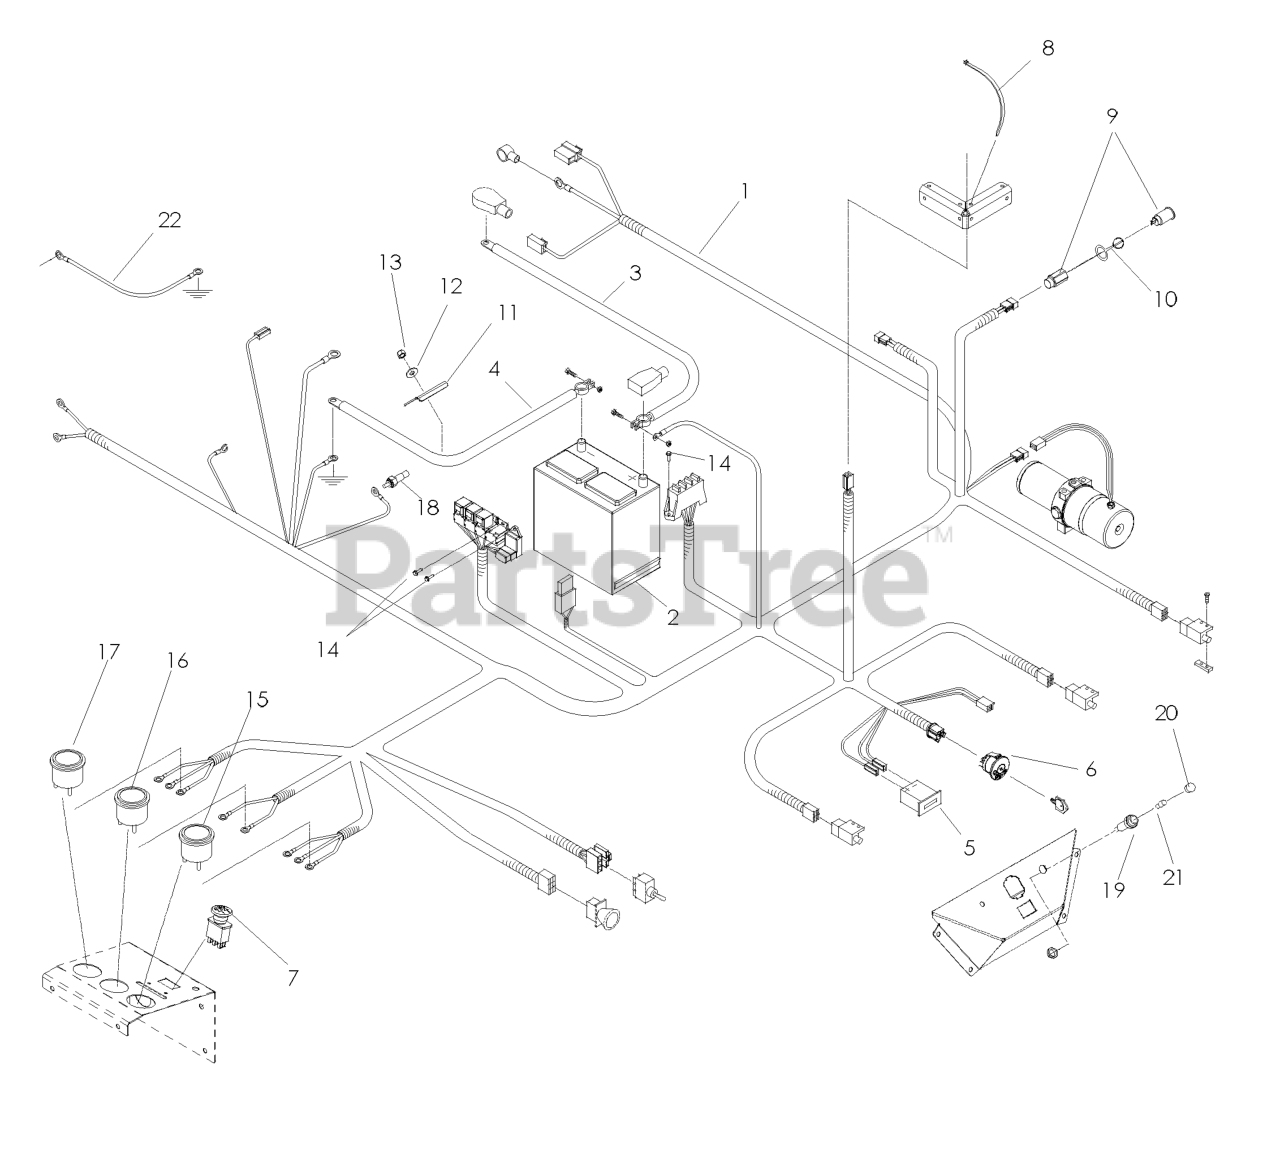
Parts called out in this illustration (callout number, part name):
3	CABLE, POS.
4	CABLE, NEG.
5	HOUR METER
6	RP IGNITION SWITCH
7	SWITCH, PTO 10 AMP
8	TIE, PLASTIC
9	POWER SOURCING HSG
10	POWER SOURCE CAP
12	WASHER 5/16 FLAT
13	NUT 5/16 NYLOC
14	SCR #10-12X3/4 HEX WAS HD ZD
15	TEMP GAUGE DATCON #100182
16	GAUGE, AMPMETER DATCON 100160
17	GAUGE, OIL PRES DATCON 100172
18	SENDER,TEMP
19	LAMP SPROCKET
